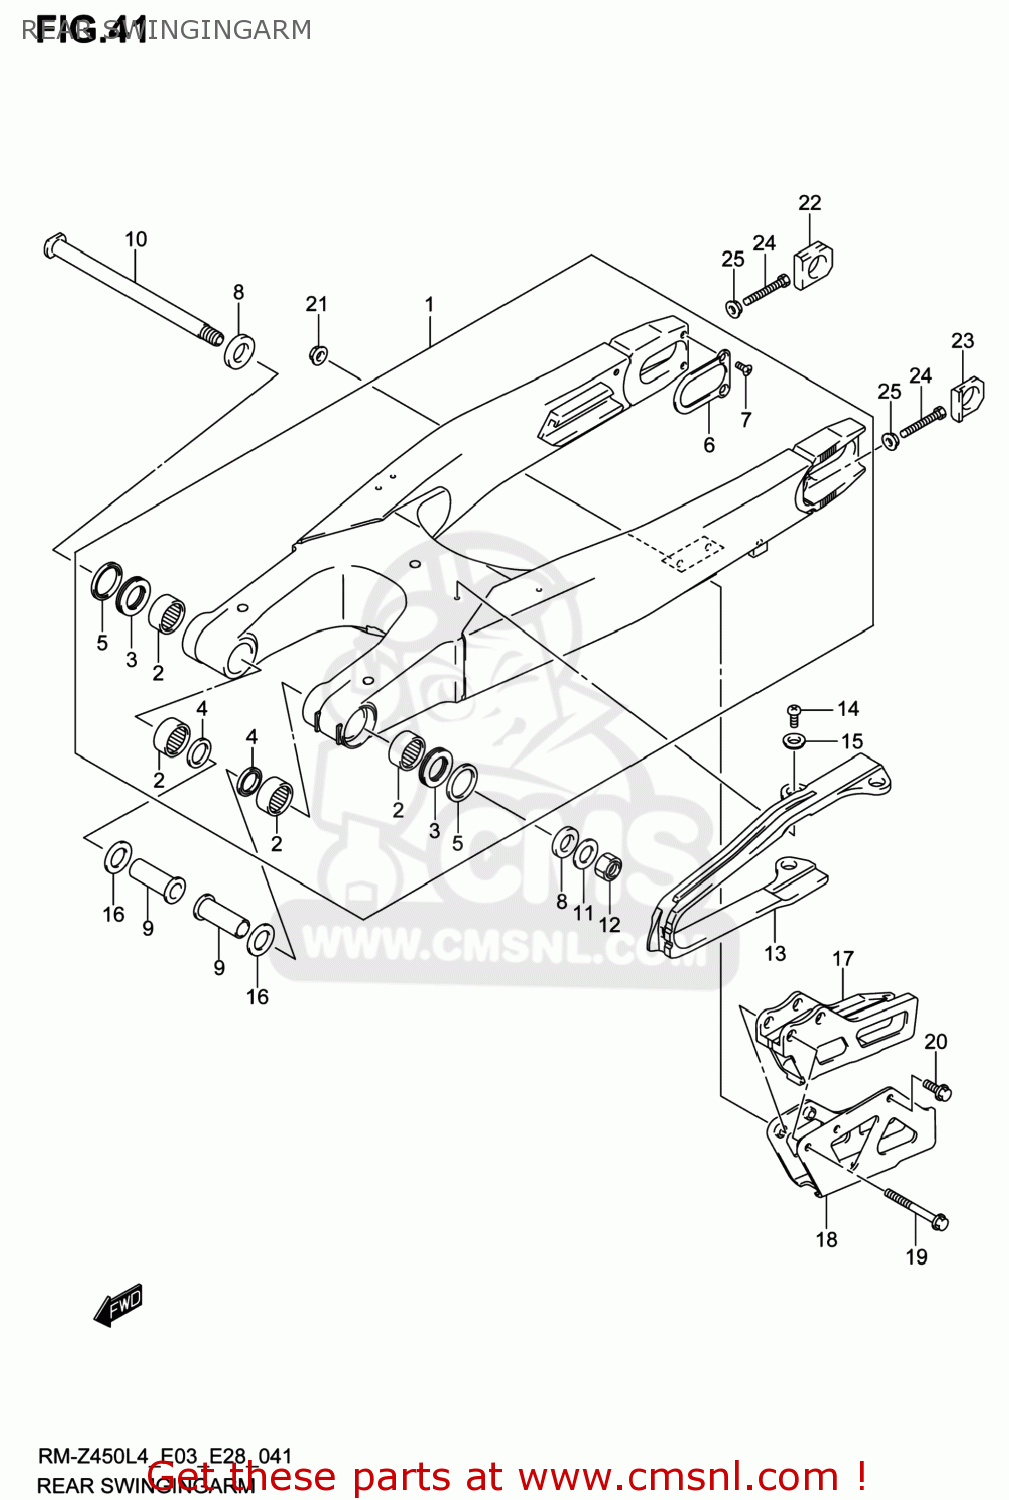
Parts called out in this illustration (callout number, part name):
1	SWINGINGARM ASSY,RR
2	BEARING(22X29X15)
3	BEARING(22X35X2)
4	SEAL,OIL(22X29X4)
5	SEAL,RR SWGARM PIVOT OUTER
6	PLATE,SWING ARM RR
7	SCREW(5X10)
8	SPACER,RR SWGARM PIVOT OUTER
9	SPACER,SWGARM PIVOT INNER
10	SHAFT,RR SWINGINGARM PIVOT
11	WASHER
12	NUT
13	BUFFER,CHAIN TOUCH DEFENSE
14	SCREW
15	WASHER
16	WASHER
17	GUIDE,CHAIN
18	PLATE,CHAIN GUIDE
19	BOLT(6X45)
20	BOLT(6X12)
21	NUT
22	WASHER,CHAIN ADJUSTER,R
23	WASHER,CHAIN ADJUSTER,L
24	BOLT(8X50)
25	NUT
